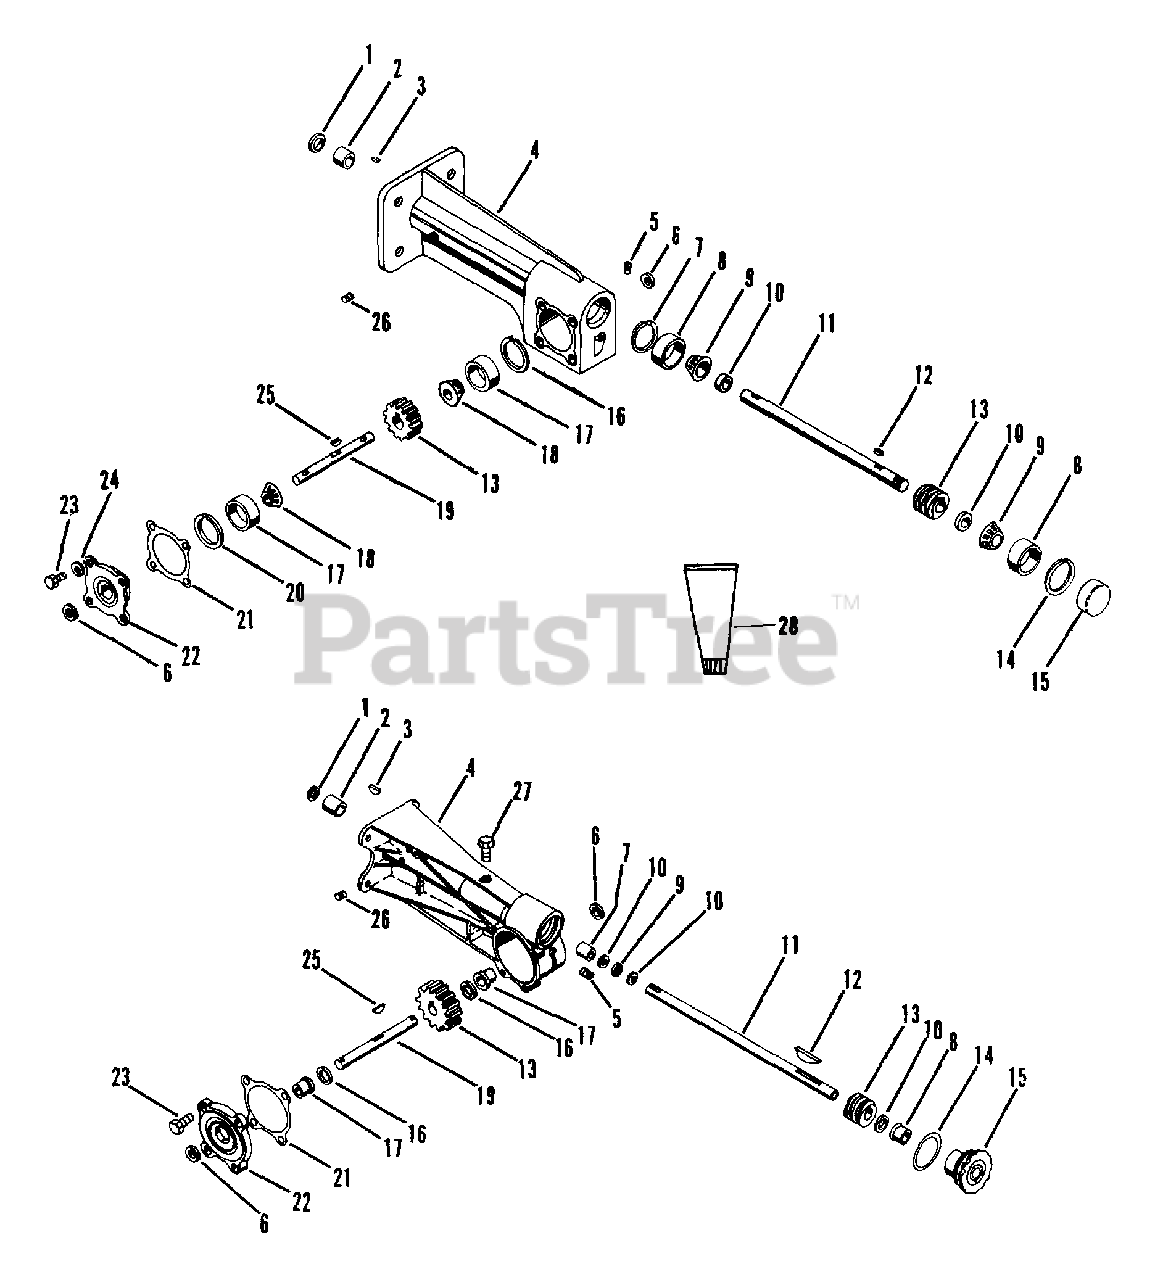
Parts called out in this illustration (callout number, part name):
1	SEAL .750X1.000X.125
2	BRG-NEEDLE .750X1.0X.62
2	BSHG-SLV .750X1.000X1.000
3	KEY-WDRF .188X.875X.375 SAE11
4	WORM GEAR HOUSING
4	GEARCASE - ALUMINUM
5	PIPE PLUG
6	SEAL 1.000X1.980X.375
7	RG-RTNG-INT 1.781X.062
7	BSHG-SLV .750X1.000X.750
8	BRG-CUP 1.781X.475
8	BSHG-FLG .750X1.000X.750X1.132
9	BRG-CONE .750X.61
9	BRG-N THRST .754X1.24X.078
10	BSHG, SPCR .755X1.12X.50 PM
10	WSHR-HDND-THRST .755X1.40X.062
11	WORM SHAFT
12	KEY-SQ .188X1.0X.188 SAE 8630
12	KEY-FTHR .188X1.38X.188
13	WORM GEAR AND WORM - KIT
13	WORM & GEAR SET
13	WORM & WORM GEAR SERVICE ASSEM
14	GASKET
14	SNAP RING KIT
15	DUST CAP
15	ADJUSTMENT PLUG
16	RG-RTNG-INT 1.969X.062
16	WSHR-HRD-THRS 1.007X1.542X.062
17	BRG-CUP1.980X.420
17	BSHG-FLG 1.000X1.25X.75X1.50
18	BRG-CONE 1.0X.58
19	TINE SHAFT
19	SUB SHAFT
20	SNAP RING KIT
21	GASKET
22	BEARING FLANGE
22	COVER
23	BLT-HEX .31-18X.88 PL GR2
23	SCR-TAP .312-18X1.0 HWH PL TR
24	WSHR-LK .312X.097 PL HVY
25	KEY-WDRF .25X.875X.375 SAE A
25	KEY-WDRF .25X.687X.375
25	KEY-WDRF .188X.625X.25 SAE 61
26	BREATHER
27	SCR-TAP .375-16X .50 HWH PL TR
28	ARIENS 16 OZ.BOTTLE OF L2 LUBE
